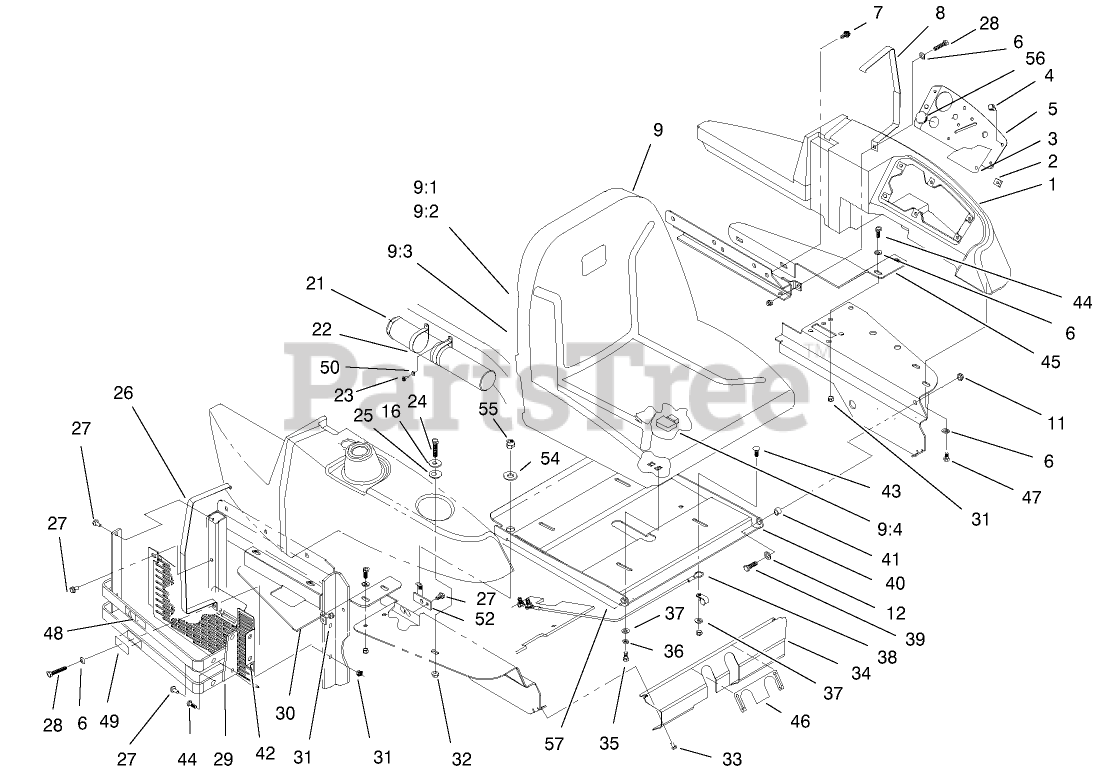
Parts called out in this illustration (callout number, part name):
1	CONSOLE
2	CLIP-TINNERMAN
3	DECAL - INSTRUMENT
4	SCREW-PPH
5	PANEL - INSTRUMENT
6	WASHER-PLAIN
7	SCREW-HWHTF
8	STRAP-CONSOLE
9	SEAT ASM
9:1	SHELL
9:2	SEAT CUSHION KIT
9:3	EDGING
9:4	SWITCH-SEAT
11	NUT-LOCK, NI
12	WASHER-FLAT
16	WASHER
21	TUBE-MANUAL
22	CLAMP-R
23	RIVET-BLIND
24	SCREW-HH
25	BUSHING-FLANGE
26	STRAP-TANK, FUEL
27	SCREW-HWHTF
28	SCREW-HH
29	BUMPER ASM
30	PLATE-SUPPORT, TANK
31	NUT-LOCK, NI
32	NUT-HHF, WHIZ
33	SCREW-HWH
34	PLATE - COVER, FRONT
35	SCREW-HH
36	WASHER-LOCK
37	WASHER-FLAT
38	CABLE-SEAT
39	SCREW-HH
40	SEAT PLATE ASM
41	SPACER-WHEEL
42	GUARD - BELT
43	BOLT-CARR
44	SCREW-HH
45	PLATE - CONSOLE SUPT R
46	DECAL-CONTROL, STEERING
47	SCREW-HH
48	DECAL-WARNING
49	DECAL-SURFACE, HOT
50	WASHER-FLAT
52	LATCH ASM
54	WASHER-FLAT
55	NUT-LOCK, NI
57	FOAM - PLATE, SEAT
